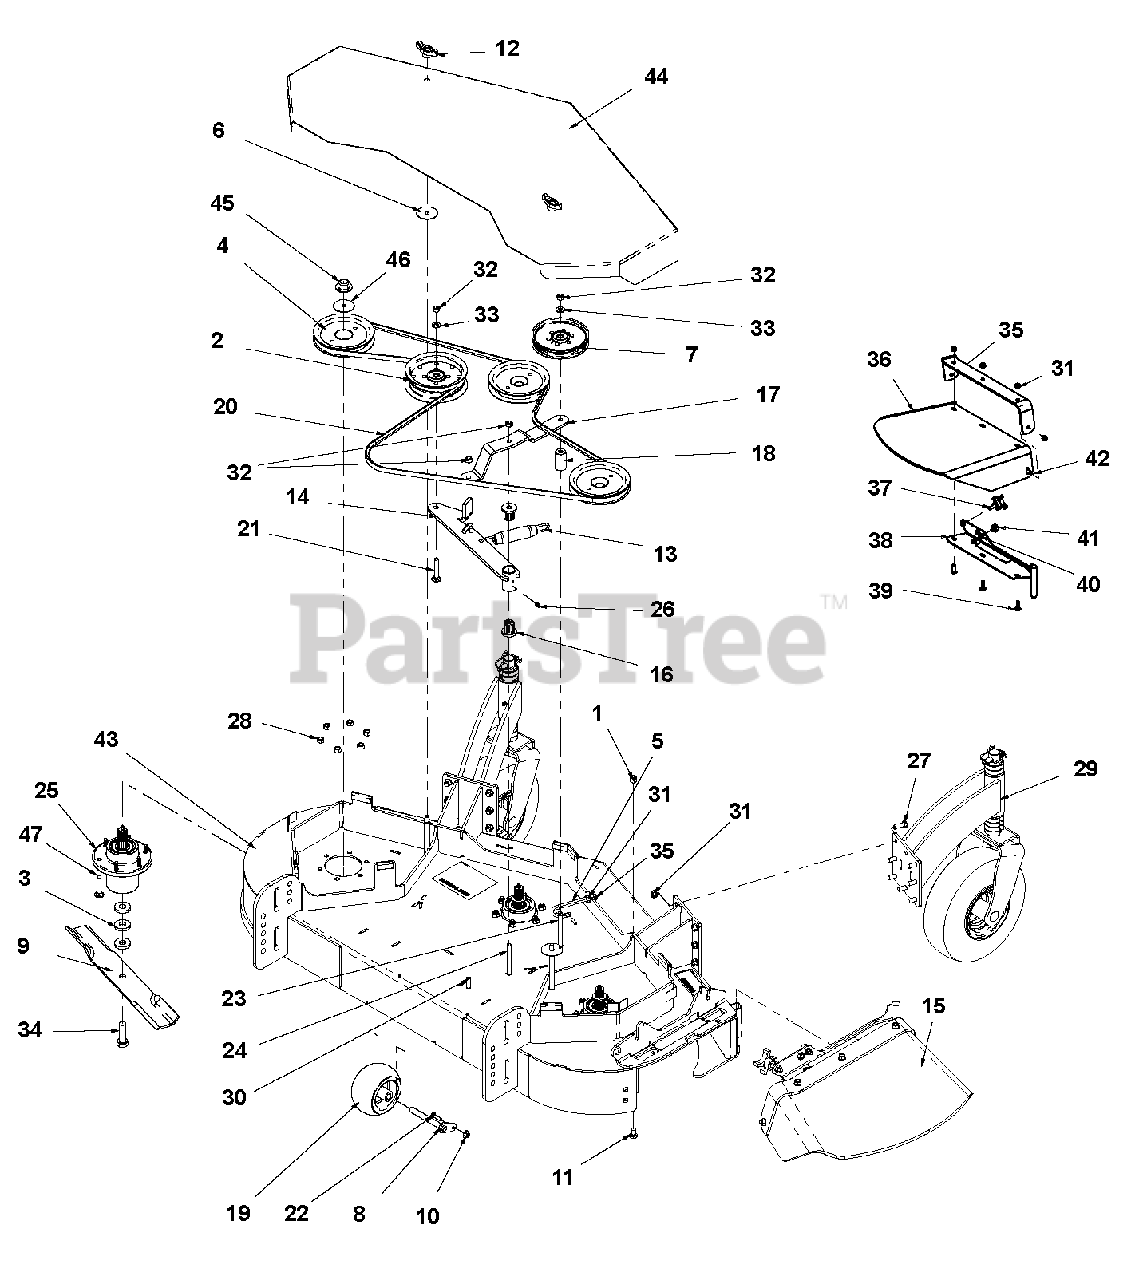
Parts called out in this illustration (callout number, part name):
1	Lochnut, .38-16 Nyloc
2	Pulley, Flat 5.0 x .38 W/Bearing
3	Washer, Blade
4	Pulley, Spline Spindle LSE
5	J-Bolt, 3/8-16 x 4.00 Y
6	Washer, .402 x 2.00 x .055 Fend Y
7	Pulley, FLAT 5.00 x .375 W/Bearing
8	Pivot, Retainer Weld
9	Blade, 18"
10	Nut-1/4" Flange Prevailing Tor
11	Bolt, .38-16 x .750 CRG 5
12	Knob, Locking
13	Spring, Tension
14	Arm, Idler
15	Assembly, Discharge Shield
16	Bearing, FLG M10 x M25 x M27 Fluted
17	Strap, Idler Pulley
19	Wheel, Gage
20	BELT, HB 109.3 EL AMD
21	Bolt, 3/8-16 x 2.25 CRG 5 Y
22	Bolt, 1/4-20 x 1.00 SQU SN Y
23	Bolt, 3/8 x 4 Short Neck Round Head
24	Bolt, 3/8-16 x 3.50 CRG 5 Y
25	Assembly, Spindle Housing
26	Fitting, 1/4-28 Straight Grease Zerk
27	Bolt, 3/8-16 x 1.00 Hex 5 Y
28	Nut, 3/8-16 STD Hex GR5 Y
29	Assembly, Wheel & Strut (see page 26 for parts)
30	Bolt, 3/8-16 x 1.25 CRG 5 Y
31	Locknut, 3/8-16 Whiz Y
32	Locknut, 3/8-16 Crown Y
33	Washer, .406 x .813 x x .065 Flat Y
34	Bolt, Hex .62-11 x 2.00 Grade 8
35	Strap, Rubber Discharge
36	Shield, Rubber Discharge
37	Knob, 3/8 x 1.25-4 Prong
38	Weldment, Discharge
39	Bolt, Round Head Square Neck .38-16 x 1.25 Grade 5
40	Locknut, 5/16-18 Whiz
41	Bumper, Rubber
42	Bolt, Round Head Square Neck .38-16 x 1.00 Grade 5
43	Weldment, 52 Gravely Deck w/Decals
44	Weldment, 52 Gravely Deck Shield w/Decal
45	Locknut, 3/4-16 Crown
46	Washer, .75 x 1.312 x .120
47	Bolt, .38-16 x 1.25 Round Head Square Neck
